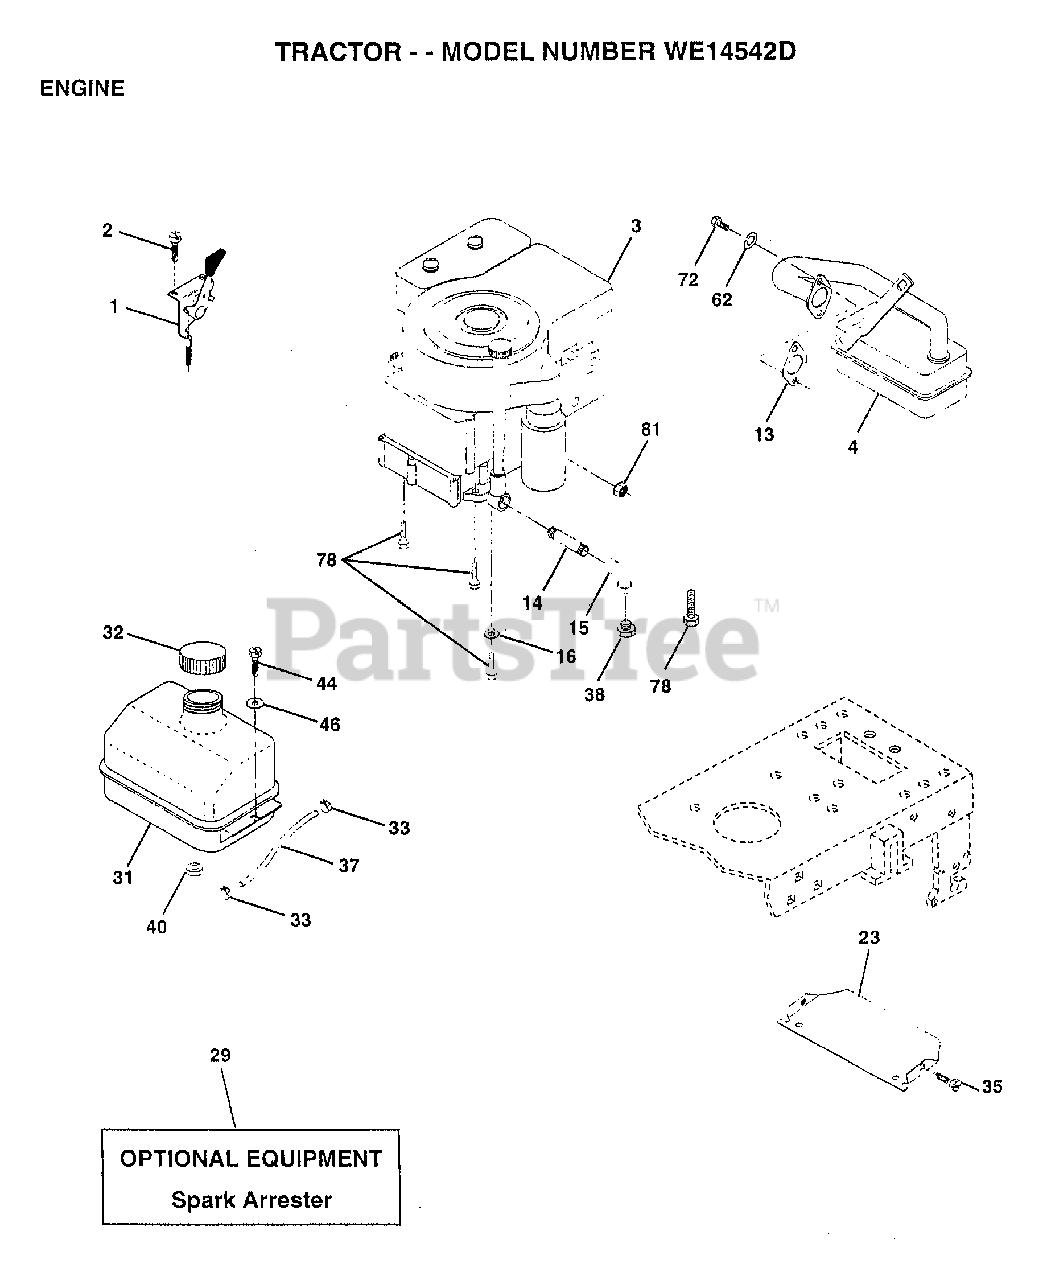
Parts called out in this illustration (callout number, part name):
1	CONTROL THROTTLE
2	SCREW LT
4	MUFFLER
13	GASKET ENG 1 313 LD TIN PLATED
14	PIPE NIPPLE
15	ELBOW
16	LOCKWASHER
23	SHIELD-HEAT
31	TANK.FUEL.LT.
32	CAP ASM FUEL
33	HOSE CLAMP
35	SCREW
37	LINE FUEL
44	SCREW HEX CRT
46	WASHER
62	LOCKWASHER
72	SCREW
78	SCREW
81	NUT
